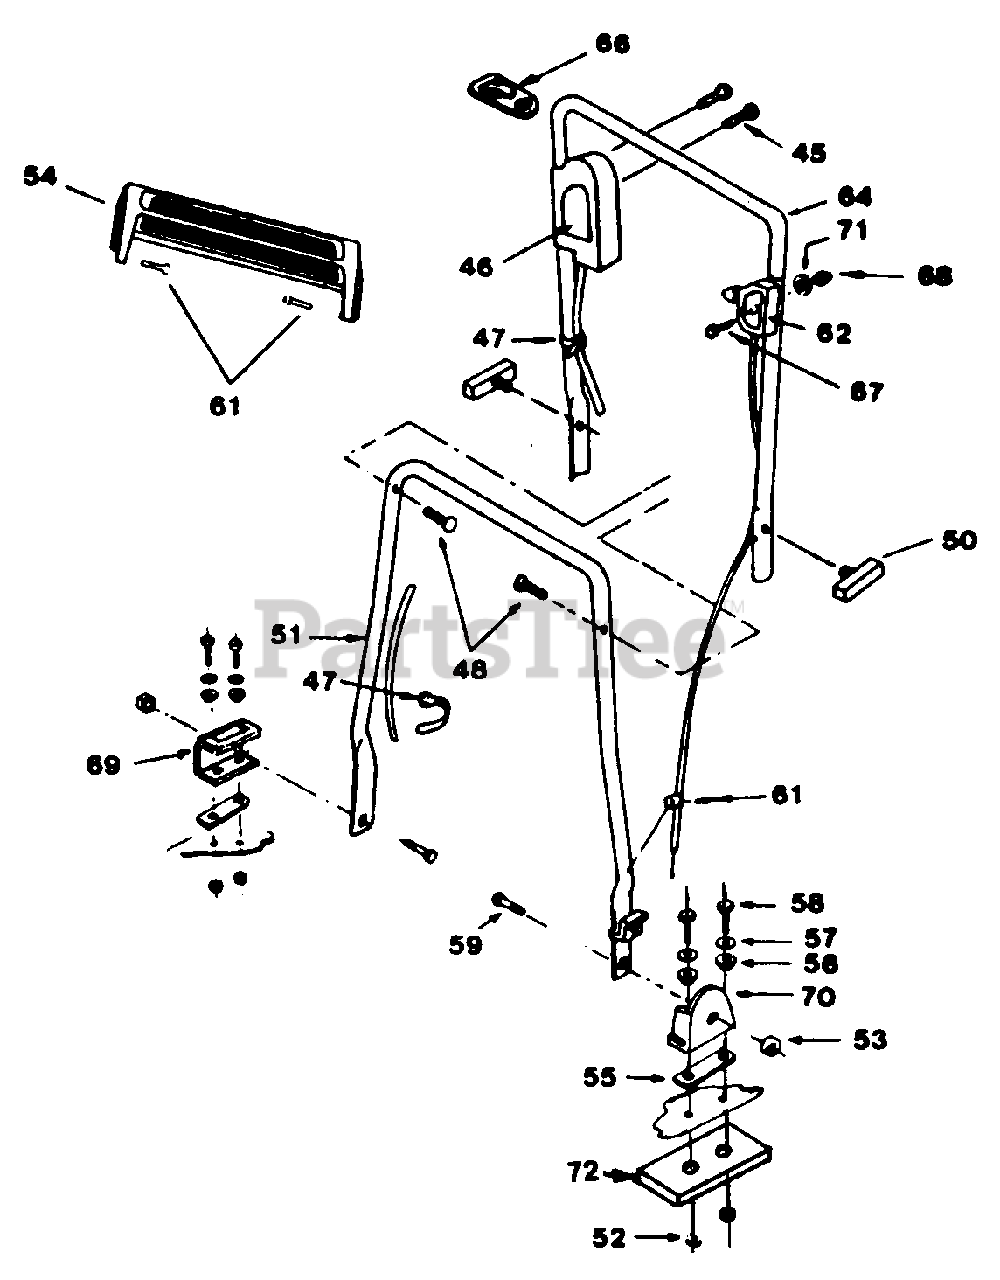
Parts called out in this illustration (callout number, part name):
45	Screw
46	Label - Switch Box
47	Plastic Tie
48	Curved Hd. Screw
50	Locking Knob
51	Lower Handle Assy.
52	Nut 1/4 - 20
53	Nut 3/8- 16
54	Trim Plate
55	Insulator Strip
56	Insulator
57	Flat Washer
58	Screw, 1/4 - 20 x 1' Hex Head
59	Shoulder Bolt
61	Screw
62	Cable Release Control
64	Upper Handle
66	Strain Reliet
67	Screw 1/4 20 x 1-1/2
68	Nut 1/4 - 20 Acorn
69	Handle Bracket- R.H.
70	Handle Bracket- L.H.
71	Washer
72	Plate - Support
